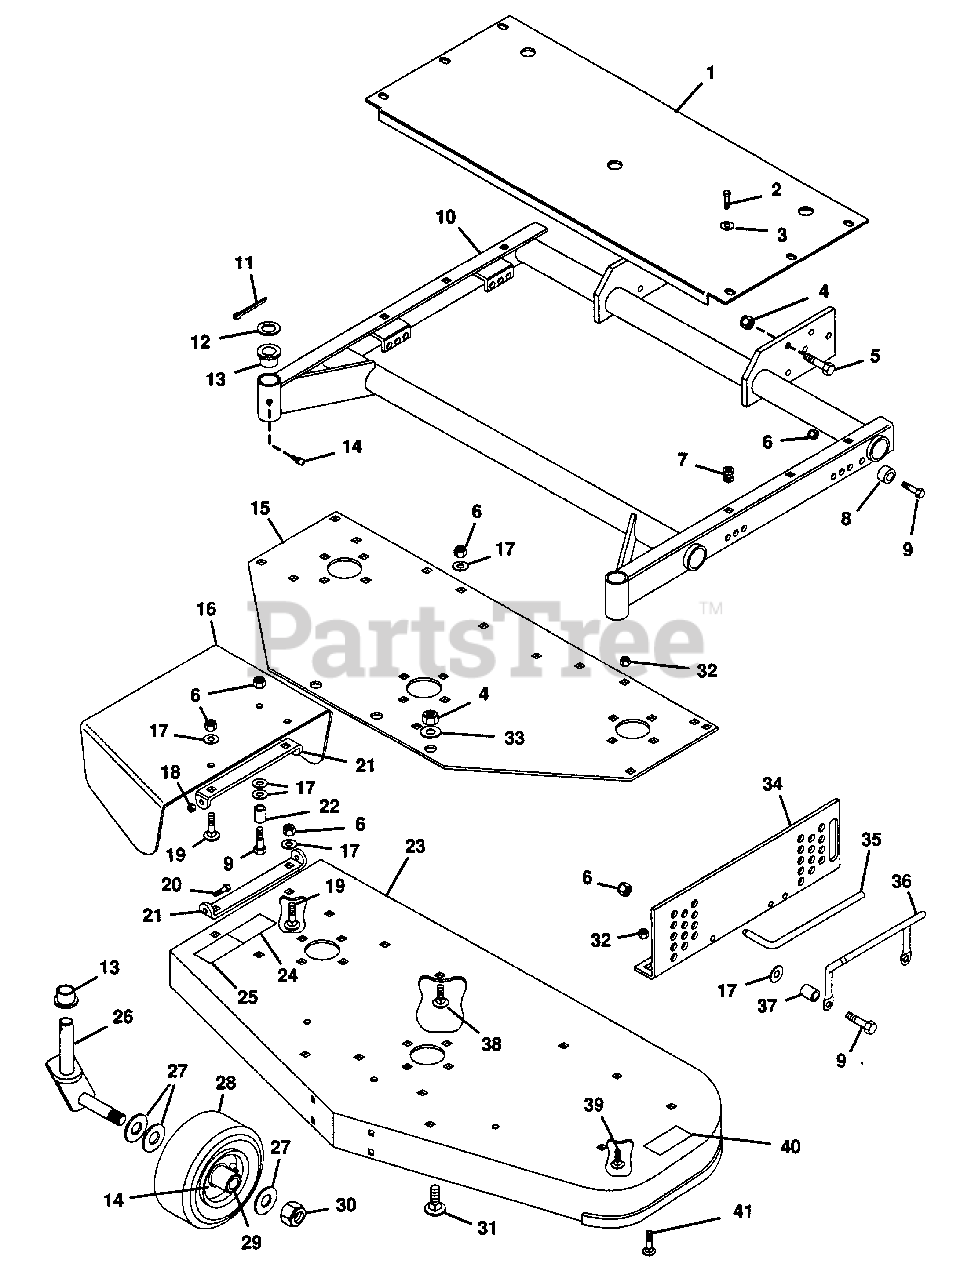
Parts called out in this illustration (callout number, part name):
1	Guard, 50" PMH Series
2	Screw, 1/4-20x.50 Self Tapping
3	Washer, Flat .281x.625x.065
4	Nut, Lock 1/2-13
5	Bolt, Hex 1/2-13x1.50
6	Nut, Lock 3/8-16
7	Grommet, Plastic
8	Bush., St. .391x.621x.676 Stl.
9	Bolt, Hex 3/8-16x1.50
10	Weldment, Mower Frame
11	Pin, Cotter .187x1.50
12	Race, Bearing Thrust
13	Bush., Flg. 1.03x1.75x.750 Ny.
14	Fitting, Lube 1/4-28
15	Plate, Support
16	Shield, Safety Ext. 50" Mower
17	Washer, Flat .406x.812x.065
18	Nut, Lock 1/4-20
19	Bolt, 3/8-16x1.00 Rd Hd Sq Nk
20	Bolt, Hex 1/4-20x.875
21	Bracket, Chute
22	Stop, Chute
23	Weldment, 50" Mower Fabricated
24	Decal, Danger Hand
25	Decal, Warning Eye
26	Weldment, Caster Fork
27	Washer, Flat .812x1.496x.134
28	Wheel, Gauge
29	Bearing, Gauge Wheel
30	Nut, Lock 3/4-10
31	Bolt, 1/2-13x1.00 Rd Hd Sq Nk
32	Nut, Lock 5/16-18
33	Washer, Flat .531x1.250x.100
34	Bracket, Mower Side Support L.H.
34	Bracket, Mower Side Support R.H.
35	Pin, Mower Locking
36	Handle
37	Bushing
38	Bolt, Carriage 3/8-16x.75
39	Bolt, 5/16-18x.625 Rd Hd Sq Nk
40	Decal, Danger Foot
41	Bolt, Carriage 5/16-18x1.00
